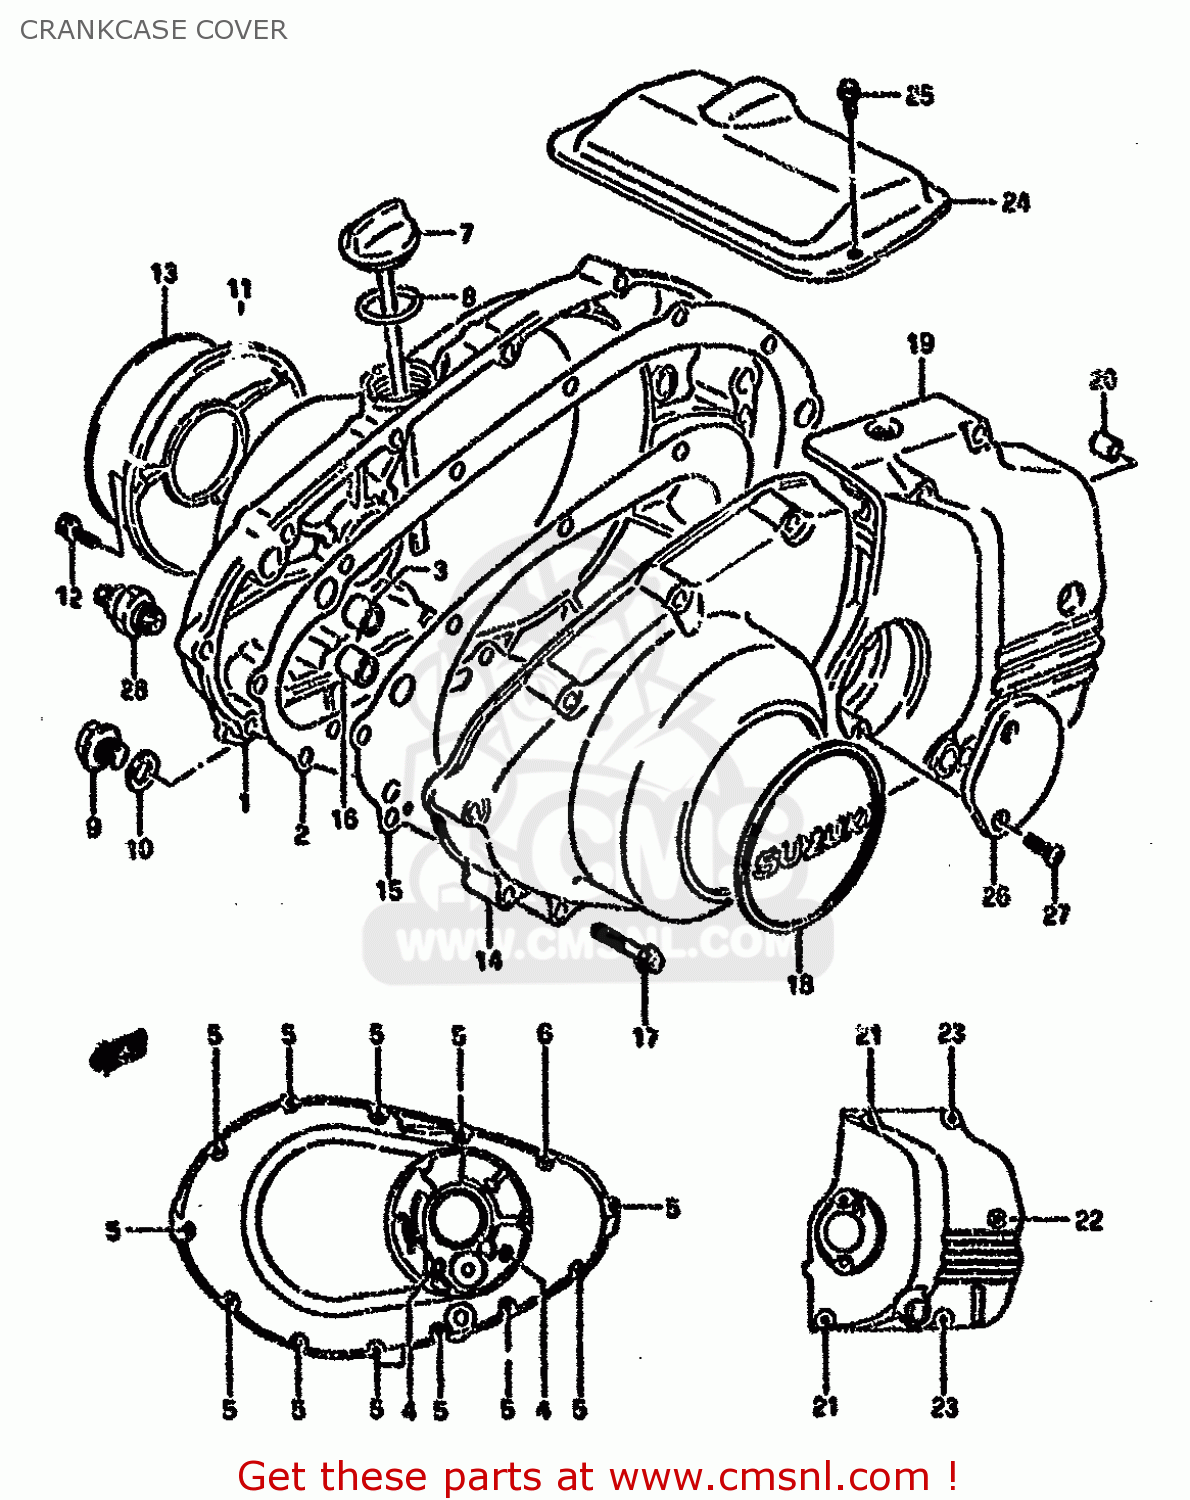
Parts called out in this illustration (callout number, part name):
1	COVER,CLUTCH
2	GASKET,CLUTCH COVER (NAS)
3	PIN
4	BOLT
5	BOLT
6	BOLT
7	GAUGE,OIL LEVEL
8	O RING(D:3.1,ID:26.4)
9	PLUG(14X12)
10	GASKET(13.8X18.8X4.8) (NAS)
11	COVER,CONTACT BREAKER
12	BOLT
13	EMBLEM,CONTACT BREAKER COVER
14	COVER,MAGNETO
15	GASKET,MAGNETO COVER (NAS)
16	PIN
17	BOLT
18	EMBLEM,CONTACT BREAKER COVER
19	COVER,ENGINE SPROCKET
20	PIN
21	BOLT
22	BOLT
23	BOLT
24	COVER,STARTER MOTOR
25	BOLT
26	CAP,CLUTCH RELEASE ADJUST
27	SCREW
28	SWITCH ASSEMBLY,OIL PRESSURE
